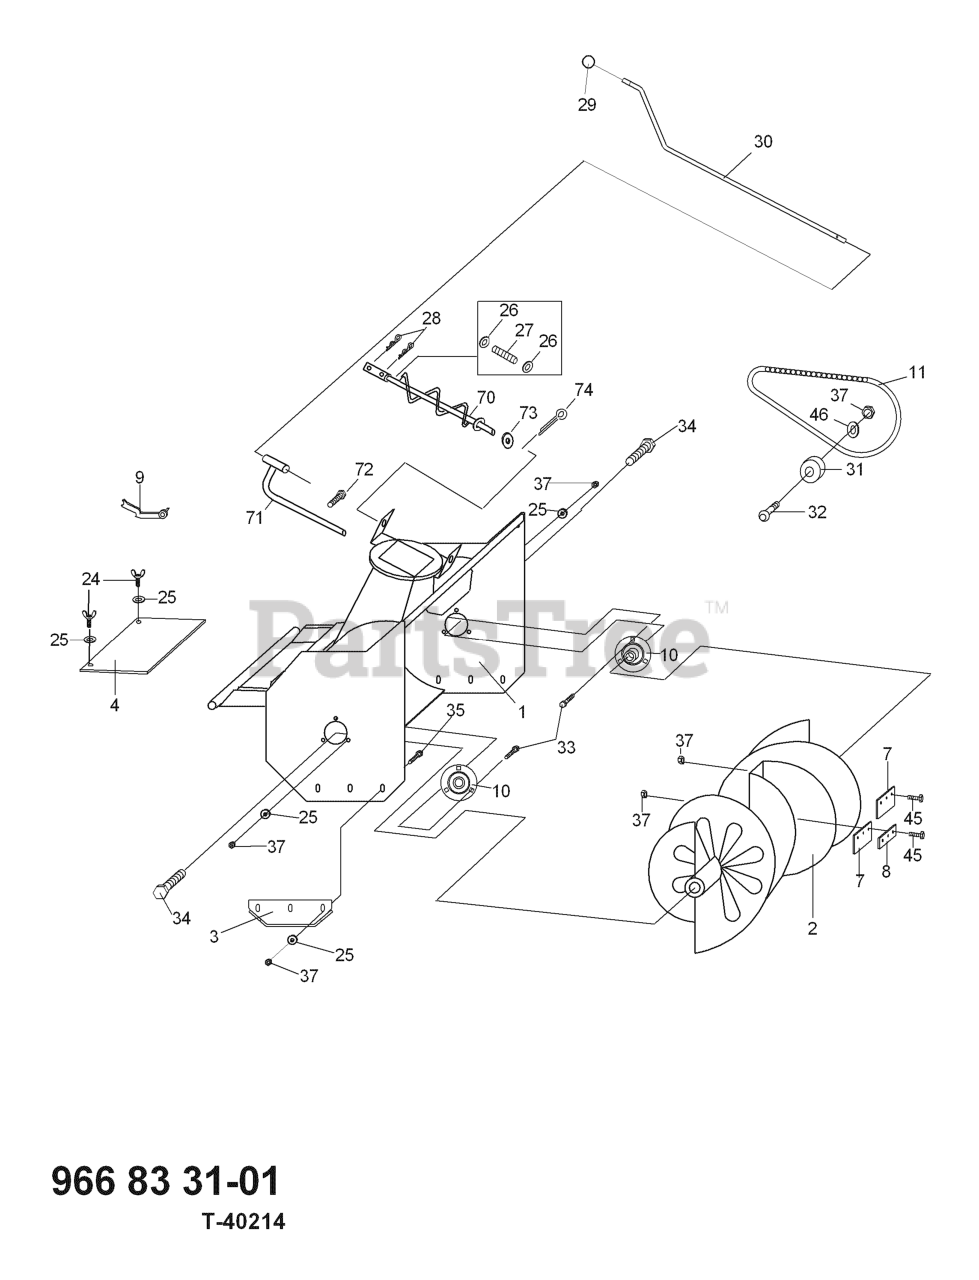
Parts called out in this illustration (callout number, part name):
7	PROTECTION
28	PIN RETAINING SCREW
31	CHAIN TENSIONER
74	PIN RETAINING SCREW
